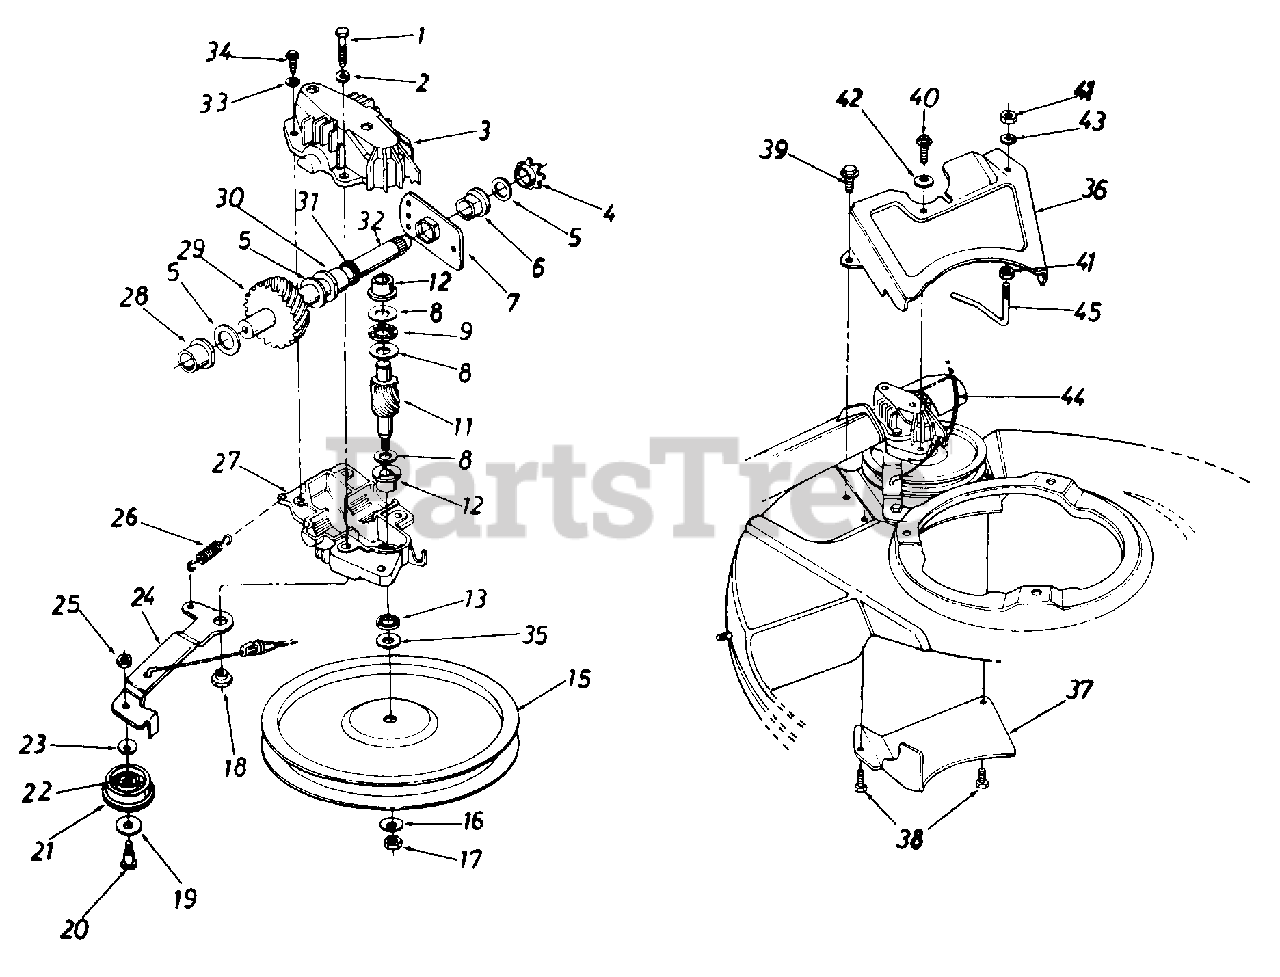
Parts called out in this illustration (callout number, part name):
1	Hex Bolt 1/4-20 x 1.25" Lg. w/ Patch
2	L-Wash. 1/4" I.D.
3	Upper Hsg. Half
4	#48 Sprocket 7 Tooth x 1/2 Pitch
5	Fl-Wash. 5/8" I.D. x .030
6	Hex Flange Brg. .631 " I.D.
8	Thrust Wash. .382" I.D. x .70" O.D.
9	Thrust Bearing .375" I.D. x .812" O.D.
11	11 Tooth Helical Gear
12	Flange Bearing
13	Oil Seal
15	Fl-Pulley 5.06" I.D.
16	Bell-Wash. .265" I.D. x 75"
17	Hex Nut 1/4-28 L.H. Thd.
18	Shld. Spacer .375" Dia. x .170
19	Fl-Wash. .390" I.D. x 1.0"
20	Shld. Bolt .375" Dia. x .40"
21	Fl-Idler Plastic 1.50" Dia.
22	Needle Brg. .375" x .31"
23	Bell-Wash. .265" I.D. x 75"
24	Idler Brk't. Ass'y.
25	Hex Patch L-Nut 1/4-28 Thd.
26	Extension Spring 1.12" Lg.
27	Lower Hsg. Half
28	Flange Bearing .56 Dia.
29	33 Tooth Helical Gear
30	Flange Bearing .629 Dia.
31	Oil Seal .625 Dia.
32	Gear Sprocket Shaft
33	L-Wash. #10 I.D.
34	Hex B-Tap Scr. #10 x .62"
35	Hex Washer .26" x .88
39	Hex AB-Tap Scr. 1/4 x .50 Lg.
40	Hex B-Tap Scr. 1/4 x .62" Lg.
41	Hex Nut 1/4-20 Thd.*
42	Bell-Wash. .265" I.D. x 75"
43	L-Wash. 1/4" I.D.
44	S. P. Cable-48" Lg.
45	S.P. Belt Guard
